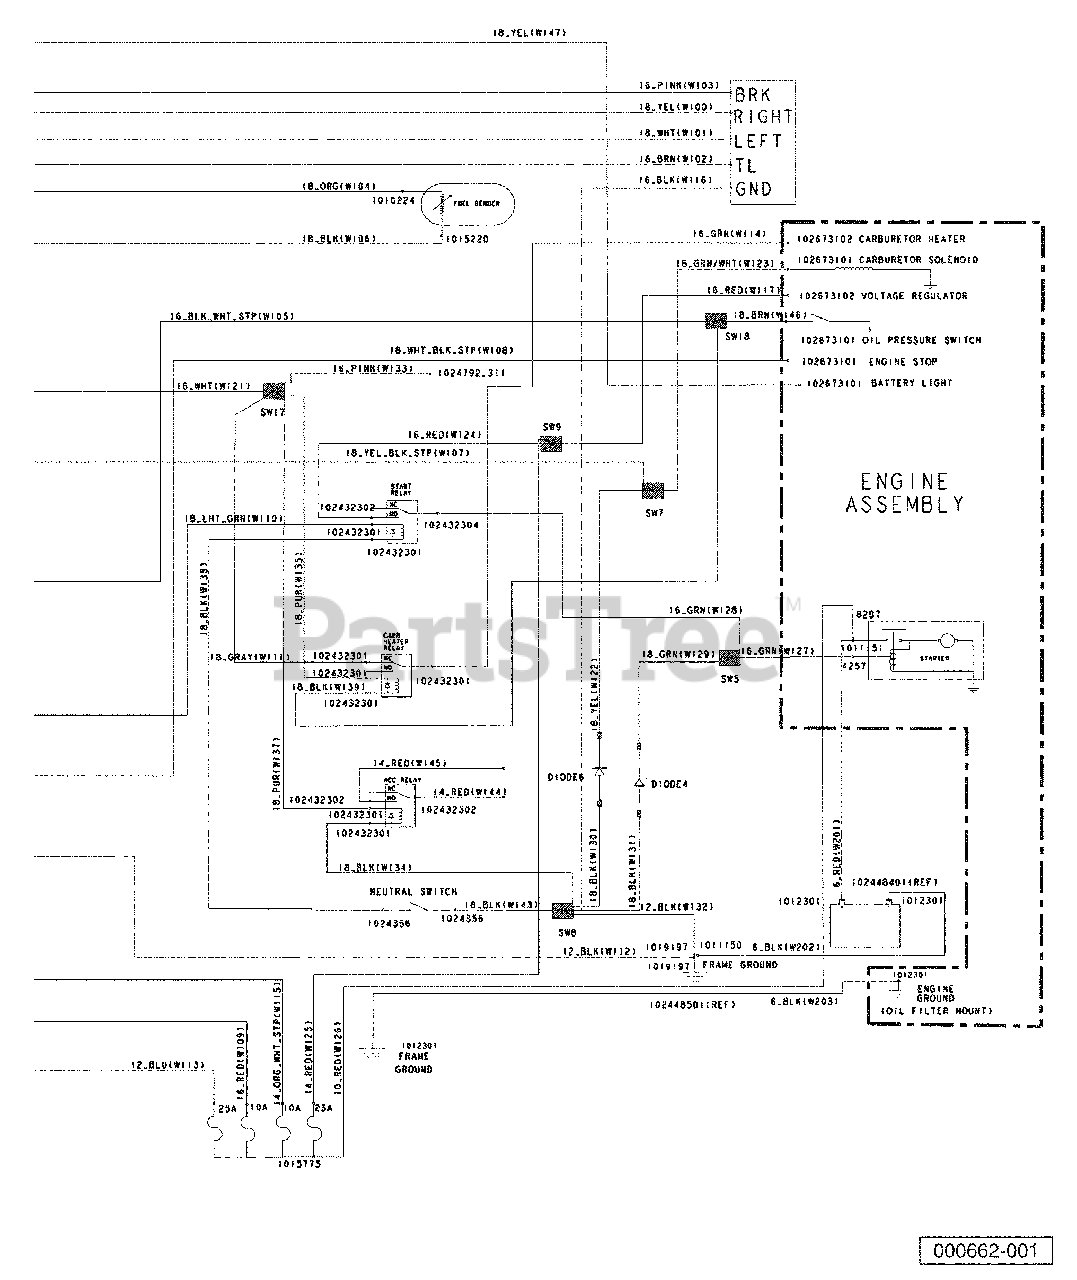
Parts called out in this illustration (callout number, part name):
1	Diode, General Purpose, 6.0a
2	Harness, AWD, Kawasaki
3	Asm, Switch, Limit, Awd
